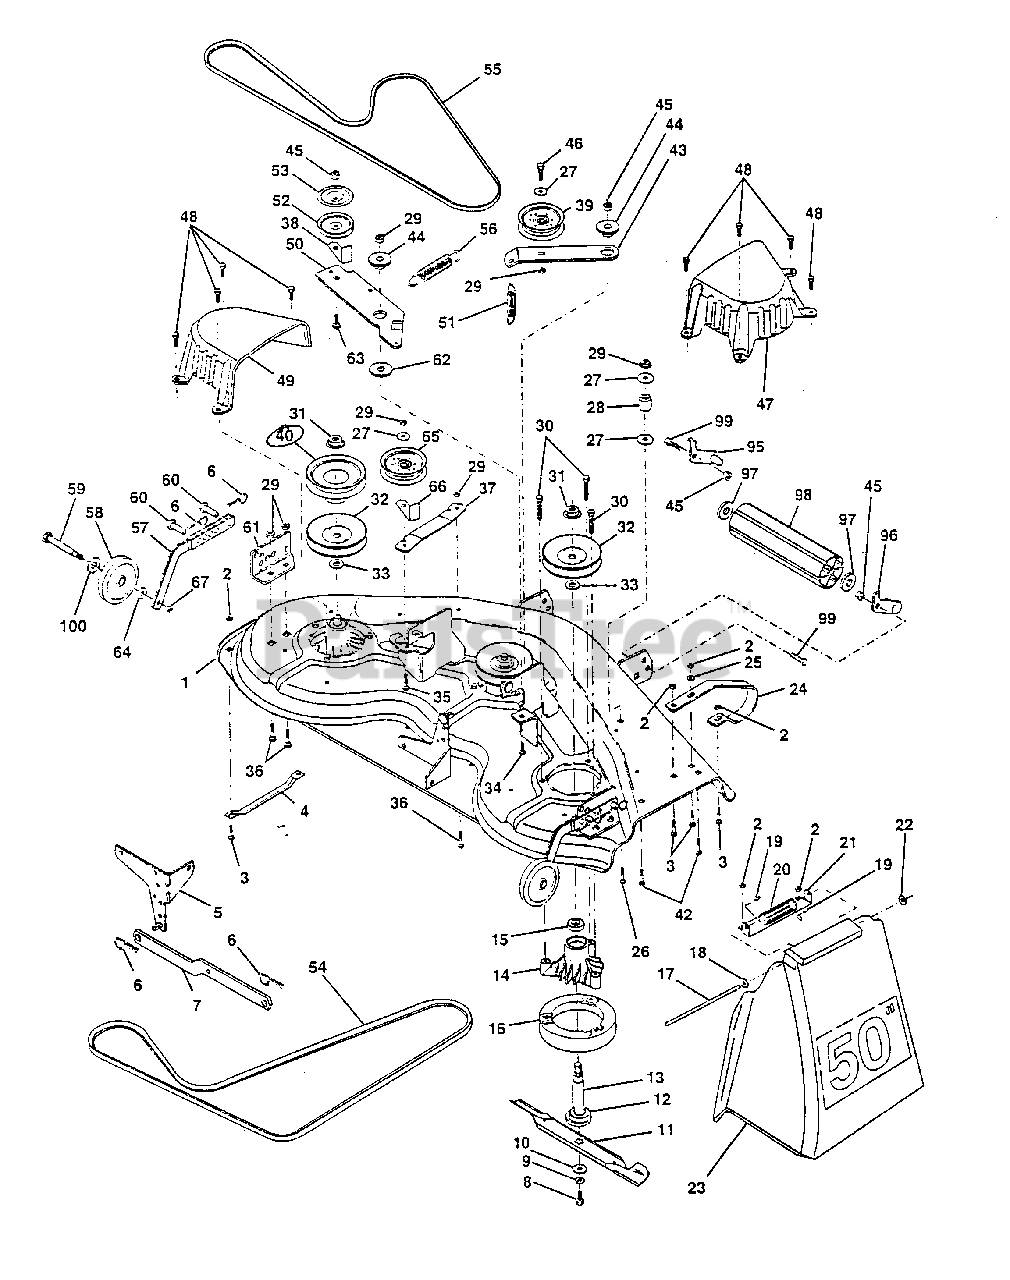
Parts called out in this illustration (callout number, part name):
1	Deck Asm., Mower 50" Vented
2	Locknut, Hex W/Ins 5/16-18 Unc
3	Bolt, Carriage 5/16-18 x 3/4
4	Runner, Mower LH
5	Bracket Asm., Sway Bar
6	Retainer, Spring
7	Arm Suspension, Rear
8	Bolt 3/8-24 x 1.25 Gr. 8 Patched
9	Washer, Lock Hvy 3/8 Unplated
10	Washer, Hard Blade Mower Vented
11	Blade (3 Required)
12	Bearing, Ball #6204 (Mandrel)
13	Shaft Asm., W/Lower Brg (Includes Key No. 12)
14	Housing, Mandrel 50" Vent
15	Bearing, Ball Mandrel
16	Stripper, Mower Vented
18	Washer 11/32 x 5/8 x 16 Ga.
20	Spring, Torsion Deflector
21	Bracket, Deflector
23	Shield, Deflector Mower
25	Washer 11/32 x 3/4 x 16 Ga.
26	Bolt, Carriage 3/8-16 x 1-3/4 Gr. 5
27	Washer 13/32 x 13/16 x 16 Ga.
28	Spacer, Spring Stop Idler
29	Nut, Lock Hex W/Wsh 3/8-16 Unc
30	Screw Thdrol Hex Head
31	Nut, Flg Top Lock Cntr 9/16
32	Pulley, Mandrel
33	Washer, Spacer Mower Vented
34	Bolt, Carriage 3/8-16 x 1-1/4
35	Bolt, Carriage 3/8-16 x 2
36	Bolt, Carriage 3/8-16 x 1 Gr. 5
37	Stiffener, Arm Idler
38	Keeper, Belt Idler
39	Pulley, Idler Flat
40	Pulley, Driven
42	Bolt, Carriage 5/16-18 Unc x 3/4
43	Arm, Idler Secondary
44	Spacer, Retainer
45	Nut, Crownlock 3/8-16 Unc
46	Bolt, Fin Hex 3/8-16 Unc x 1-3/4
47	Cover, Mandrel RH
48	Screw, Thd Roll 1/4-20 x 5/8
49	Cover, Mandrel LH
50	Arm, Idler Primary
51	Spring, Secondary
52	Pulley, Idler V Groove
53	Shield, Idler
54	V-Belt, Mower Primary
55	V-Belt, Mower Secondary
56	Spring, Primary
57	Bar Asm., Wheel Gauge
59	Bolt, Shoulder
61	Bracket, Wheel Gauge
62	Washer Hardened
63	Bolt Carriage 3/8-16 x 1-1/2
64	Washer 3/8 x 7/8 x 14 Ga.
65	Pulley Idler Flat Mower
66	Keeper, Belt Idler 50" Vent
67	Nut, Center Lock 3/8-16
95	Bracket, Asm. Noseroller LH
96	Bracket, Asm. Noseroller RH
97	Washer 17/32 x 7/8 x 16 Ga.
99	Bolt, Fin Hex 3/8-16 x 1
100	Washer 17/32 x 15/16 x 12 Ga.
